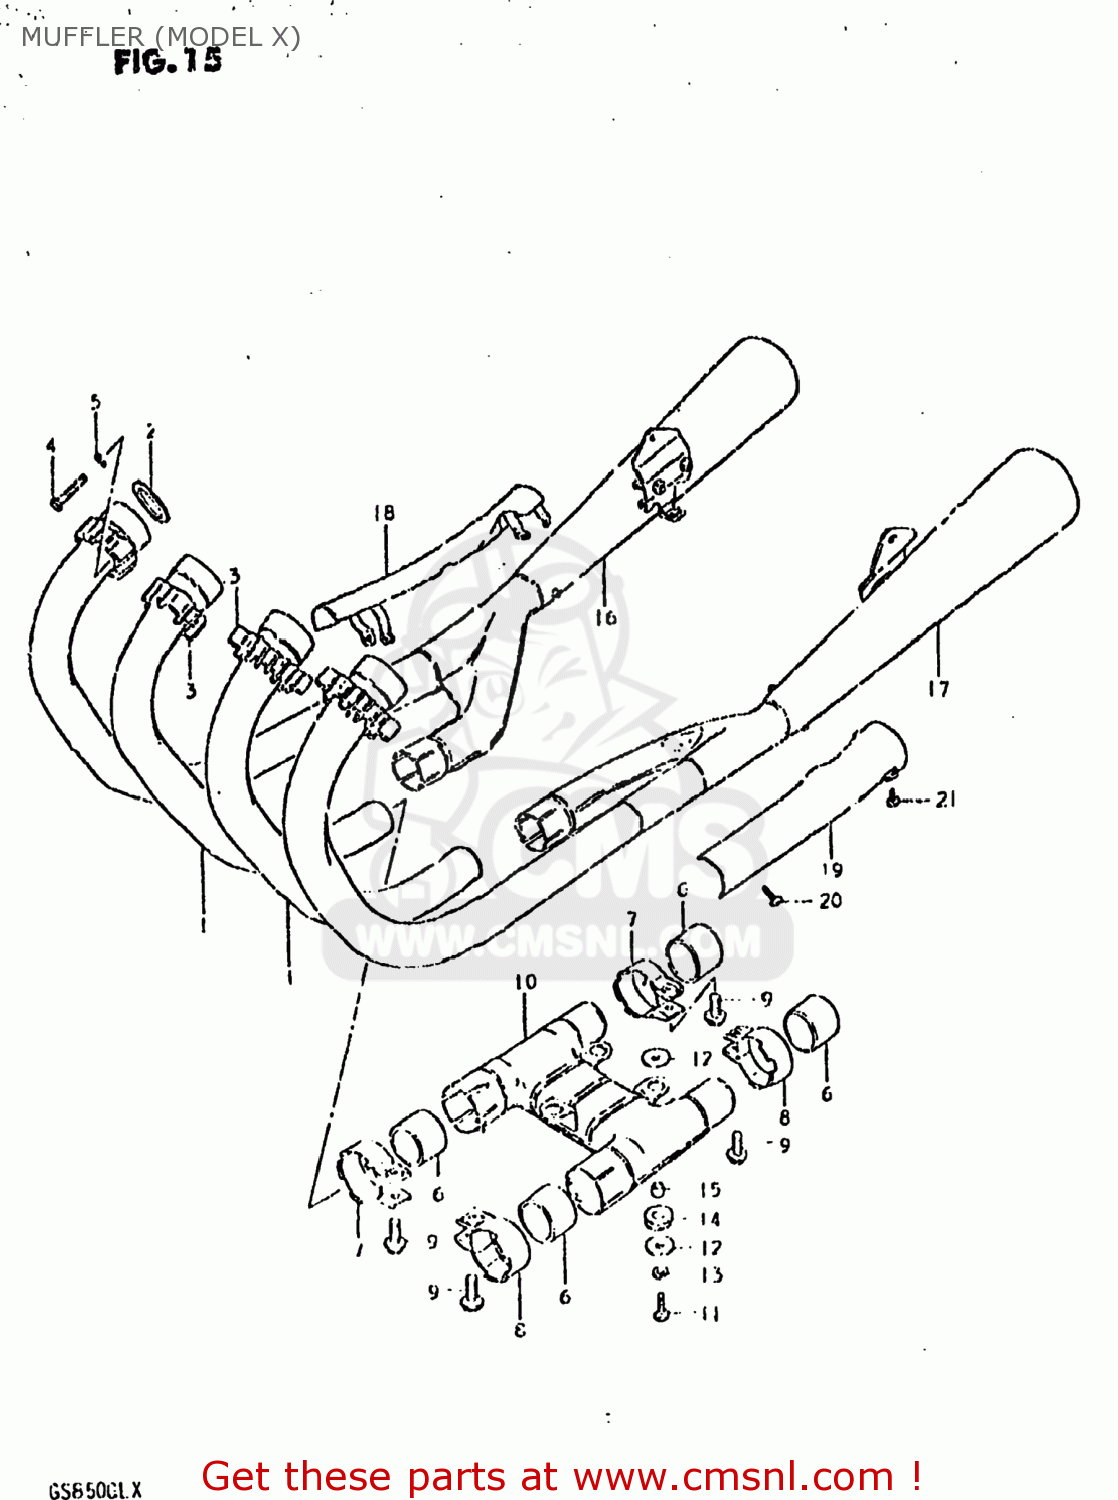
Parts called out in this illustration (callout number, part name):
1	PIPE,CENTER EXHAUST
2	GASKET,EXHAUST PIPE (NAS)
3	CLAMP,EXHAUST PIPE
4	BOLT
5	LOCK WASHER
6	CONNECTOR,MUFFLER
7	CLAMP,MUFFLER CONNECTOR,R
8	CLAMP,MUFFLER CONNECTOR,L
9	BOLT
10	BODY,PREMUFFLER
11	BOLT
12	WASHER (6.5X24X1.6)
13	LOCK WASHER
14	CUSHION
15	SPACER(6.5X10.5X6.5)
16	MUFFLER ASSEMBLY
17	MUFFLER ASSEMBLY
18	COVER,MUFFLER,R
19	COVER,MUFFLER
20	SCREW
21	SCREW
